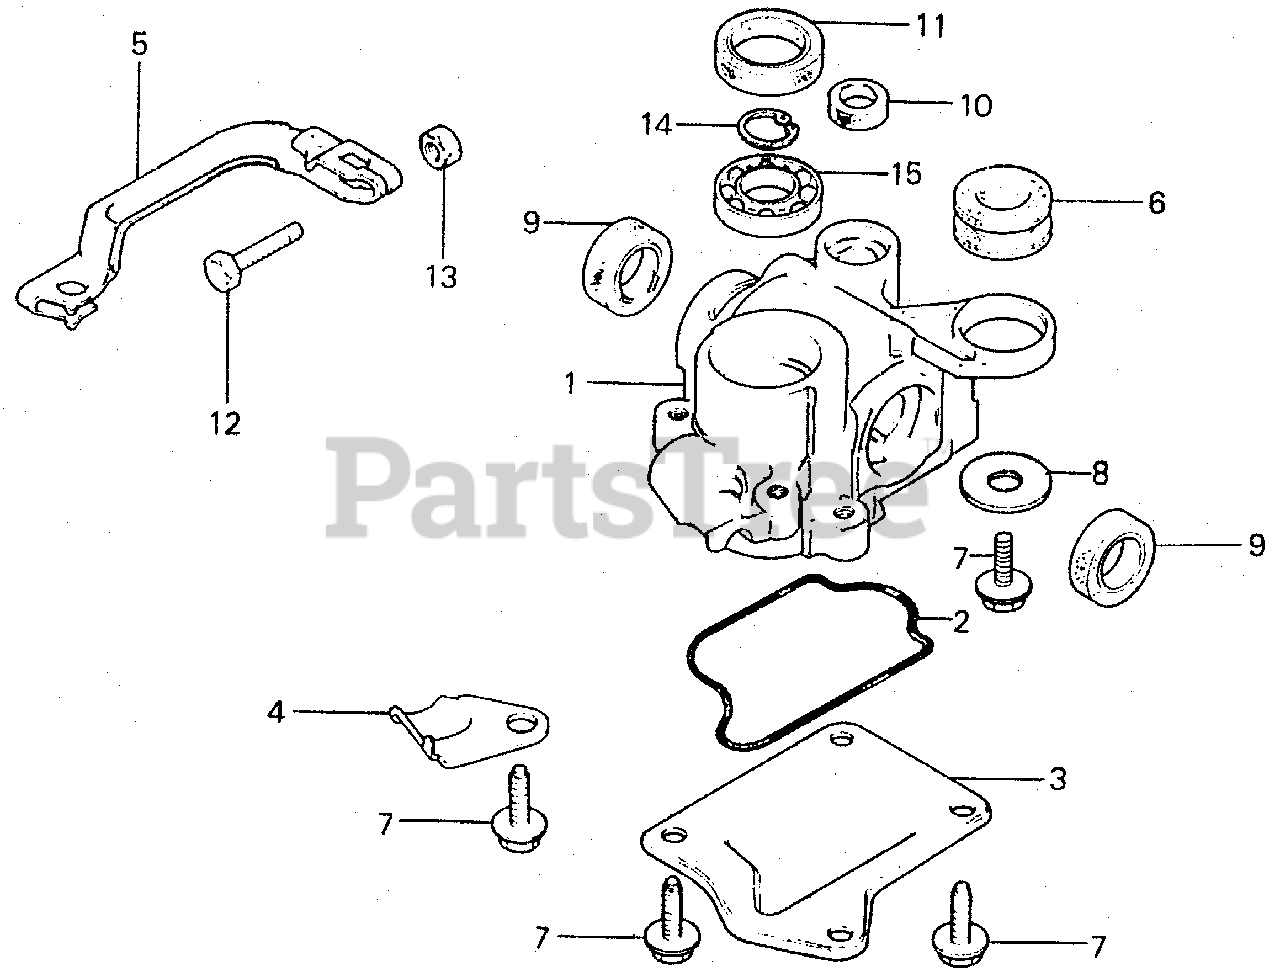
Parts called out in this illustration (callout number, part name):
1	CASE, GEAR (UPPER)
2	O-RING, CASE
3	COVER, GEAR CASE
4	HOLDER, WIRE (NOT AVAILABLE)
5	ARM, CLUTCH
6	MOUNT, RUBBER
7	BOLT, FLANGE (6X12) (CT200)
8	WASHER, SEAT (NOT AVAILABLE)
9	OIL SEAL (12X22X5)
10	OIL SEAL (8X14X5)
11	OIL SEAL (18X38X6) (NOT AVAILABLE)
12	BOLT, HEX. (6X20)
13	NUT, HEX. (6MM)
14	CIRCLIP (INNER) (28MM)
15	BEARING, RADIAL BALL (6001)
